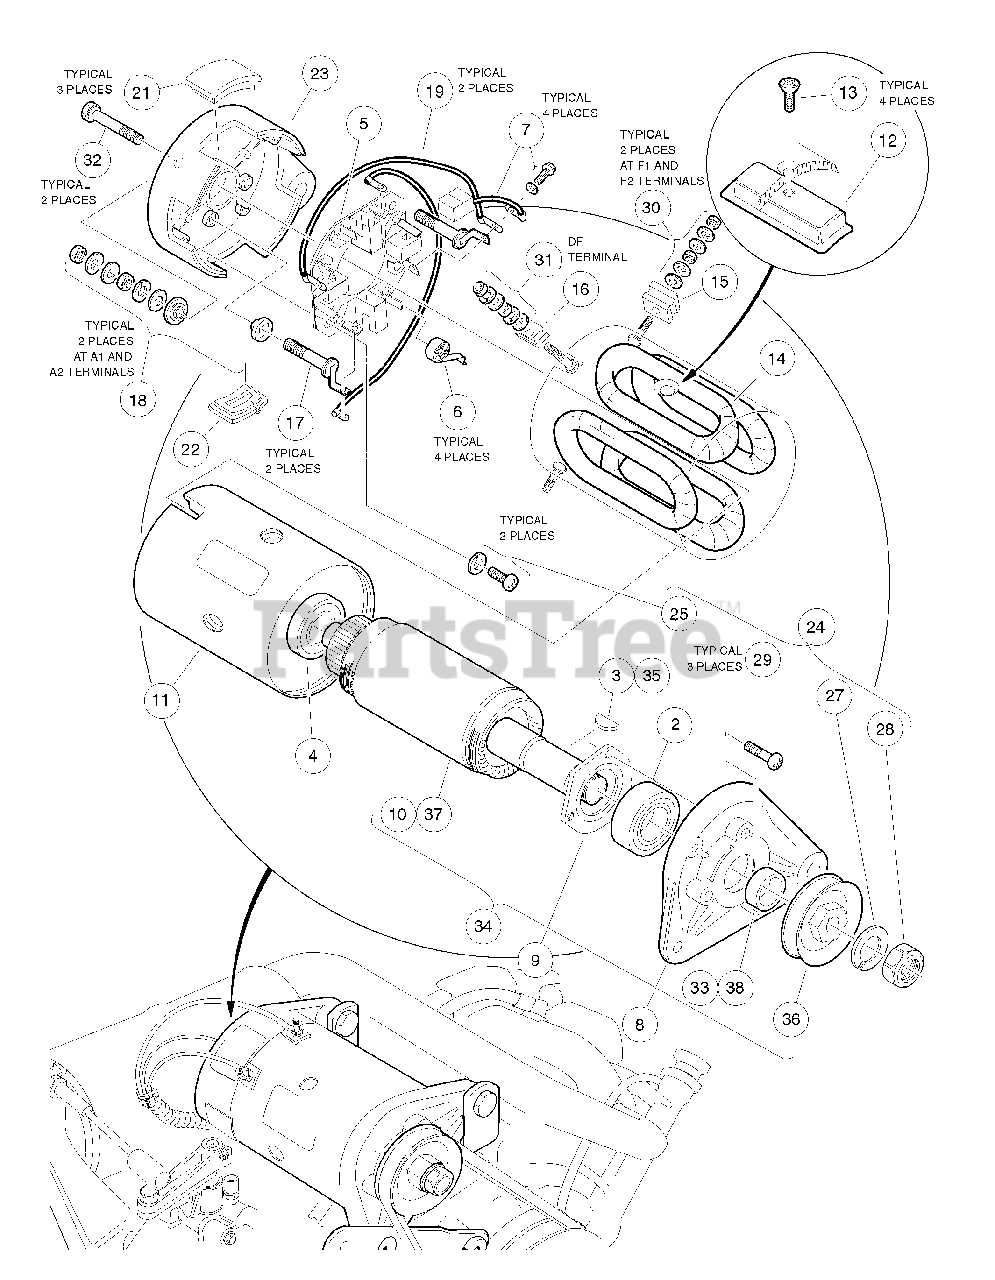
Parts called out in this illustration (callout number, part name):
1	Starter/Generator
2	Bearing, Output Shaft Ball
3	Key, Starter/Generator
4	Bearing, Ball
5	Brush Holder Assembly
6	Brush Spring Set
7	Brush and Screw Set
8	Front BrackGt
10	Armature
11	Field Coil Housing
14	Field Stator Coil Assembly
15	F Insulator Set
16	DF Insulator
17	A Connector
18	Screw and Mold Assembly
19	Brush Connector Assembly
20	Cover Set
21	Brush Inspection Port Cover
22	Brush Port Cover w/Drain
23	Rear Bracket
24	Nut and Screw Set
25	Brush Holder Asm Screw
26	Washer, M5 Flat
27	Washer, M14 Lock
30	Nut and Washer Set
31	Nut and Washer Set
32	Through Bolt Set
34	Armature Asm Conversion Kit
35	Key, Starter/Generator
36	Pulley, Starter/Generator
37	Armature
